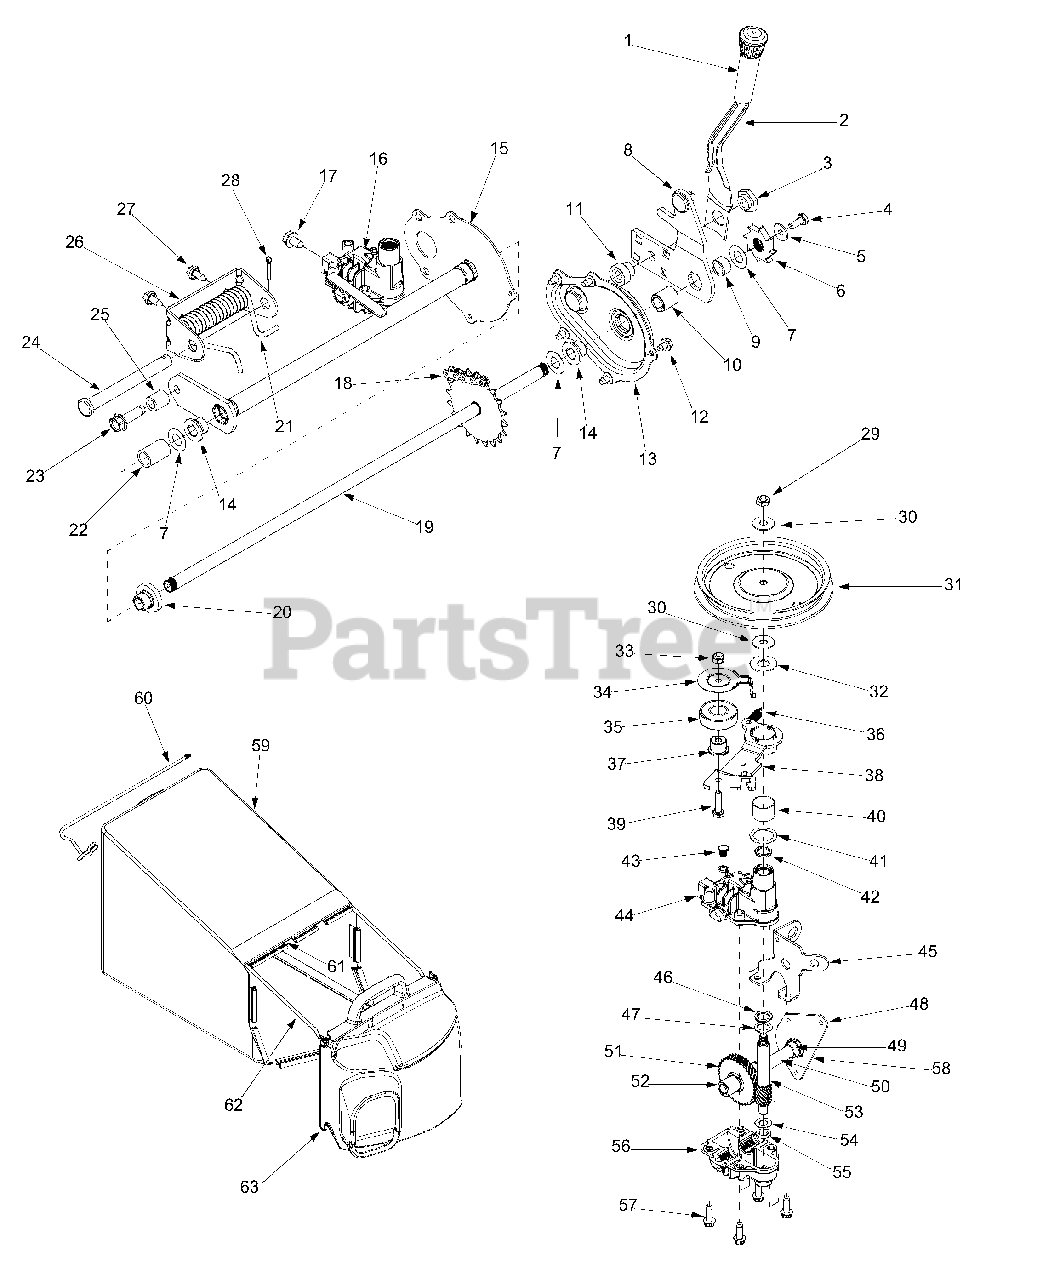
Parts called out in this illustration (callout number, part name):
2	Spring Lever
3	Shoulder Nut .825 x .165 Lg.
4	Cap Screw 1/4-20 x .620
5	Bell Washer .285 ID x .75 OD
6	Wheel Rachet
7	Flat Washer .508 ID x 1.0 OD
8	Pivot Arm Assembly
9	Spacer .510 ID x .70 OD
10	Sleeve Bearing .504 ID x .830 OD
12	Tap Screw 1/4-20 x .375
13	Chain Cover Assembly
14	Flange Bearing .506 ID x .590 Lg
15	Transmission Axle Assembly
16	Transmission Assembly
17	Hex Screw 5/16-18
19	Rear Axle Assembly
20	Flange Bearing .506 ID x .715 Lg
21	Torsion Spring
22	Spacer .550 ID x .750 OD
23	Screw 3/8-16 x .25
24	Clevis Pin .50 Dia x 4.82 Lg.
25	Spacer .385 ID x .624 OD
26	Hgt Adjustment Spring Bracket
27	Screw 1/4-14 x .825
28	Cotter Pin
29	Hex Jam Nut 5/16-24
30	Bell Washer .325 ID x .930 OD
32	Flat Washer .510 ID x 1.120 OD
33	Hex Jam Nut 1/4-28
34	Belt Keeper
36	Extension Spring
37	Flange Spacer
38	Idler Bracket Assembly
39	Hex Cap Screw 1/4-28 x 1.0
40	Bearing Sleeve
41	Flat Washer .885 ID x 1.45 OD
44	Upper Housing Assembly
45	Cable Bracket
47	Thrust Washer .504 ID x .70 OD
48	Pivot Bracket
49	Flange Bearing
50	Output Shaft 6T
53	Pinion Shaft 10T
54	Thrust Washer 3/8 x .70
55	Thrust Washer .388 x .625
56	Lower Housing Assembly
57	Hex Screw 1/2-20 x .75
58	Shaft Assembly
59	Grassbag
60	Support Rod w/ Rope Guide
61	Pivot Rod
62	Grassbag Frame
63	Grassbag Cover
